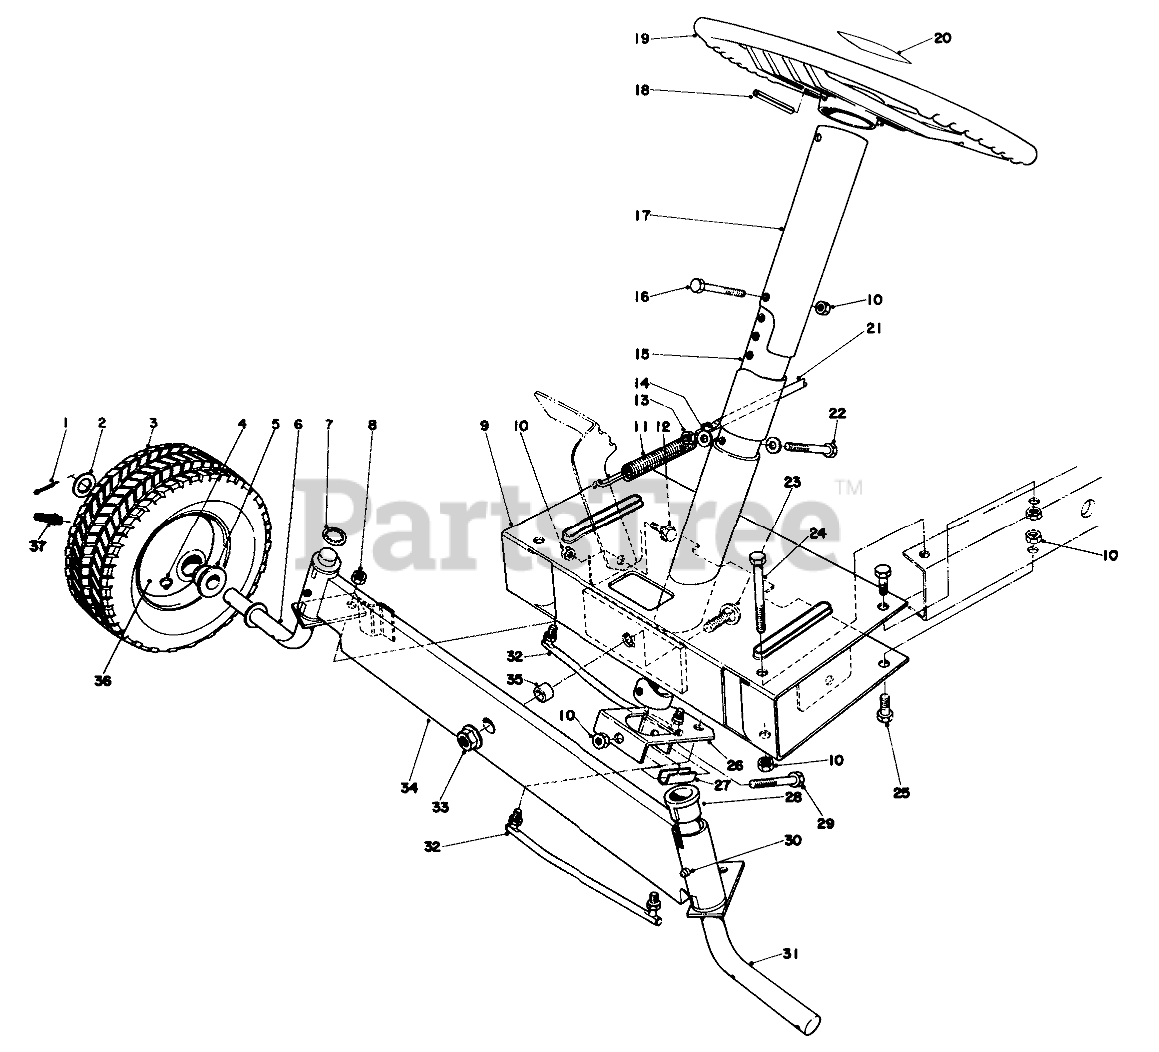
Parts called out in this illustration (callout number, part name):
1	PIN-COTTER
2	WASHER-FLAT
3	Tire Turf King
4	FITTING-GREASE
5	BUSHING
6	SPINDLE WA RH
7	RING-RETAINING
8	NUT-LOCK NI
9	Front Frame
10	NUT-LOCK, CONE
11	Brake Spring
12	SCREW-SHOULDER
13	NUT-LOCK, CONE
14	WASHER-FLAT
15	Steering Tube Inner
16	SCREW-HH
17	Steering Tube Outer
18	PIN-ROLL
19	Steering Wheel
20	Decal
21	Brake Rod
22	SCREW-HH
23	SCREW-CARR
24	SCREW-HH
25	SCREW-HH
26	Lever Steering
27	Spacer-Steering Tube
28	BUSHING
29	SCREW-HH
30	GREASE FITTING
31	Spindle L.H.
32	TIE ROD ASM
33	NUT-HF
34	Front Axle
35	FRONT AXLE SPACER
37	STEM-VALVE
